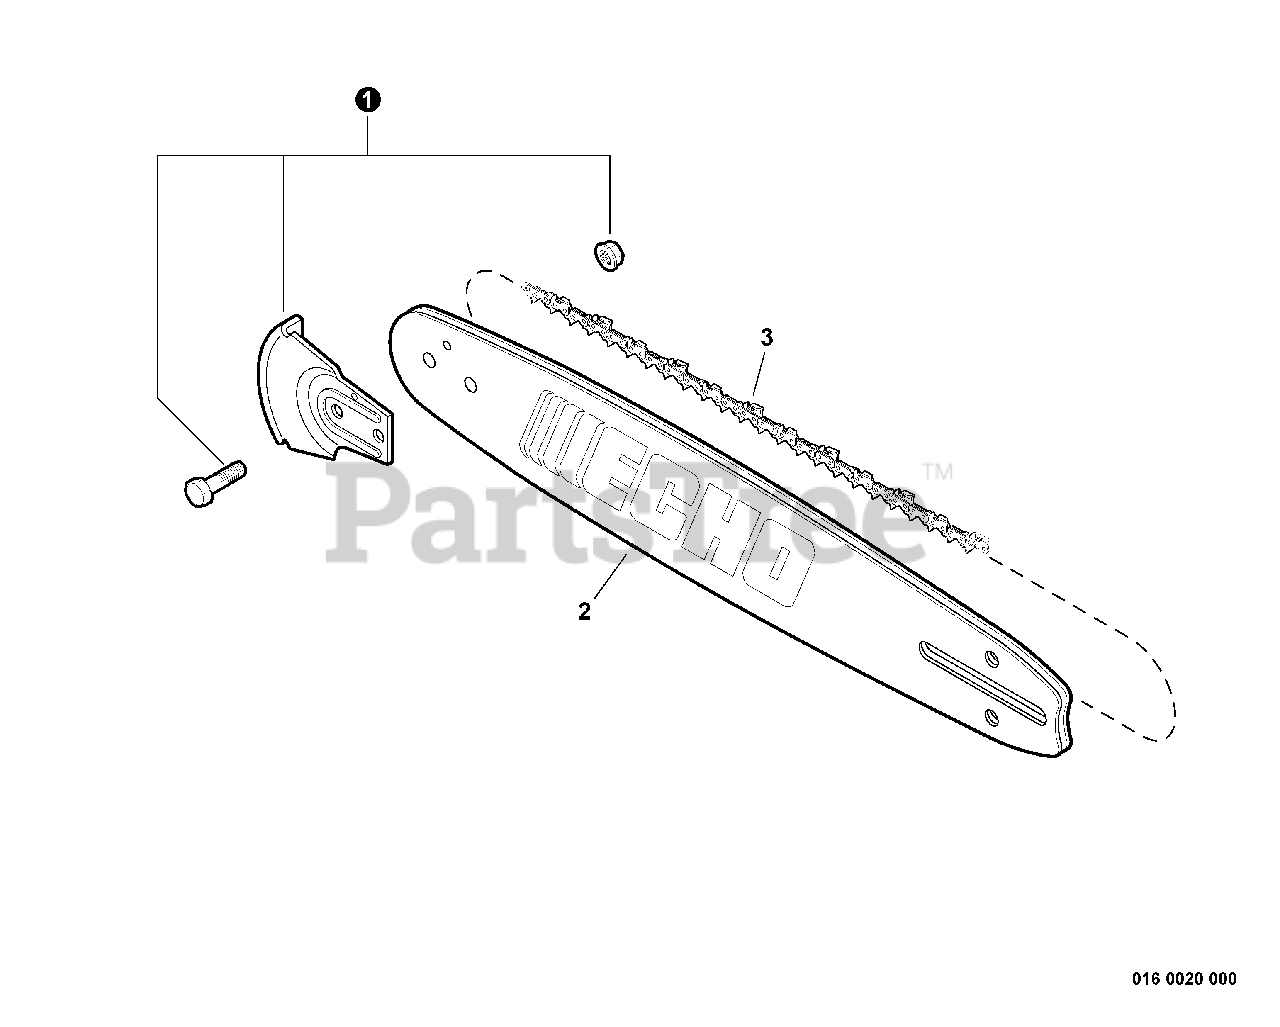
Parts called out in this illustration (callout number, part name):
1	KICK GUARD KIT
2	GUIDE BAR - 20" (50cm)
3	SAW CHAIN - 20" (50cm)
